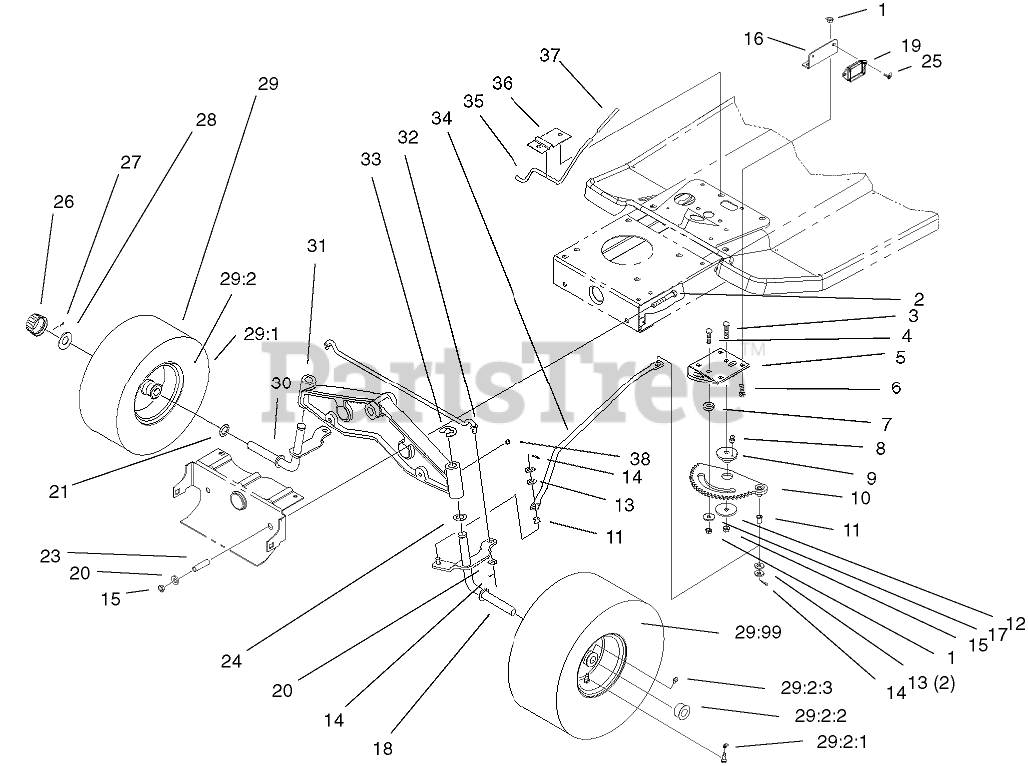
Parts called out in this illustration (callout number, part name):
1	NUT-LOCK, NI
2	SCREW-HH
3	SCREW-CARR
4	SCREW-CARR
5	BRACKET-RACK, STEERING
6	BOLT-CARR
7	SPACER-RACK, STEERING
8	FITTING-GREASE
9	BUSHING-ECCENTRIC
10	RACK-STEERING
11	BUSHING-FLANGED, NYLON
12	WASHER-BEARING
13	WASHER-FLAT
14	PIN-COTTER
15	NUT-LOCK, NI
16	BRACKET-MODULE
17	WASHER-PIVOT
18	LH SPINDLE ASM
19	MODULE
20	WASHER-FLAT
21	WASHER-THRUST
23	SPACER
24	WASHER-THRUST
25	SCREW-HWH
26	CAP-HUB
27	PIN-COTTER
28	WASHER-PLAIN
29	Wheel&tire ASM,Front
29:2	RIM ASM
29:2:1	STEM-VALVE
29:2:2	BEARING-WHEEL
29:2:3	FITTING-GREASE
29:99	TUBE-INNER
30	RH SPINDLE ASM
31	AXLE-FRONT
32	TIE ROD-STEERING
33	E-RING
34	LINK-DRAG
35	ROD-BRAKE, PARKING
36	BRACKET-PARKING BRAKE
37	GRIP-BRAKE, PARKING
38	FITTING-GREASE
